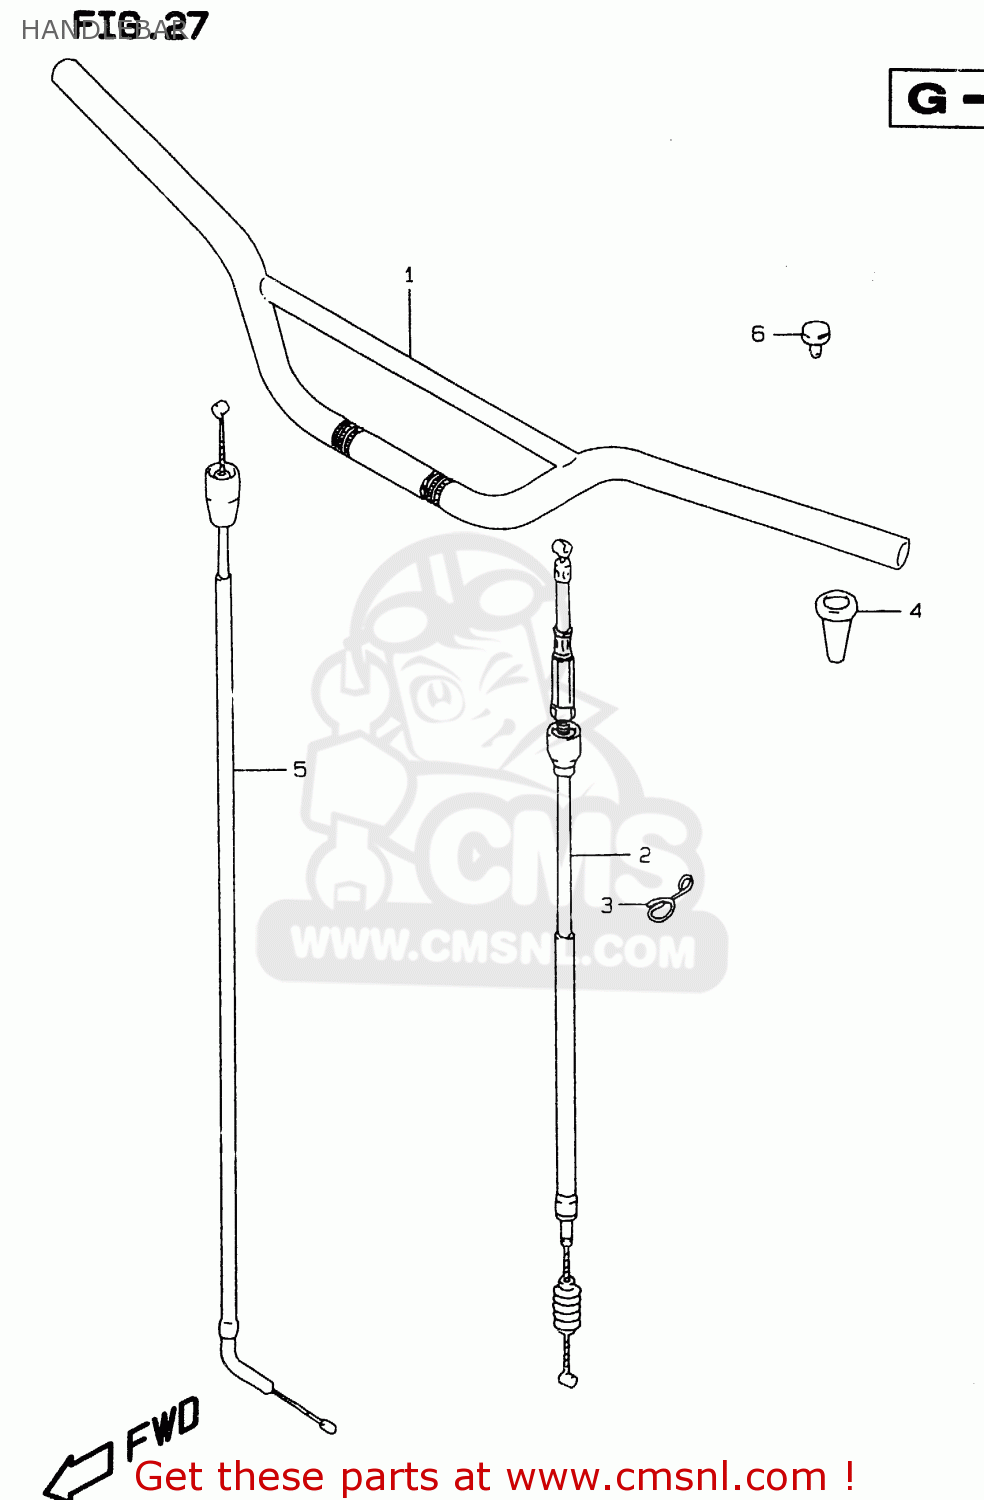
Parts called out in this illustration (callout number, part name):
1	HANDLEBAR
2	CABLE ASSEMBLY,CLUTCH
3	CLAMP,CLUTCH CABLE NO
4	BOOT, CLUTCH CABLE
5	CABLE ASSY,THROTTLE
6	CAP(OD:14)
